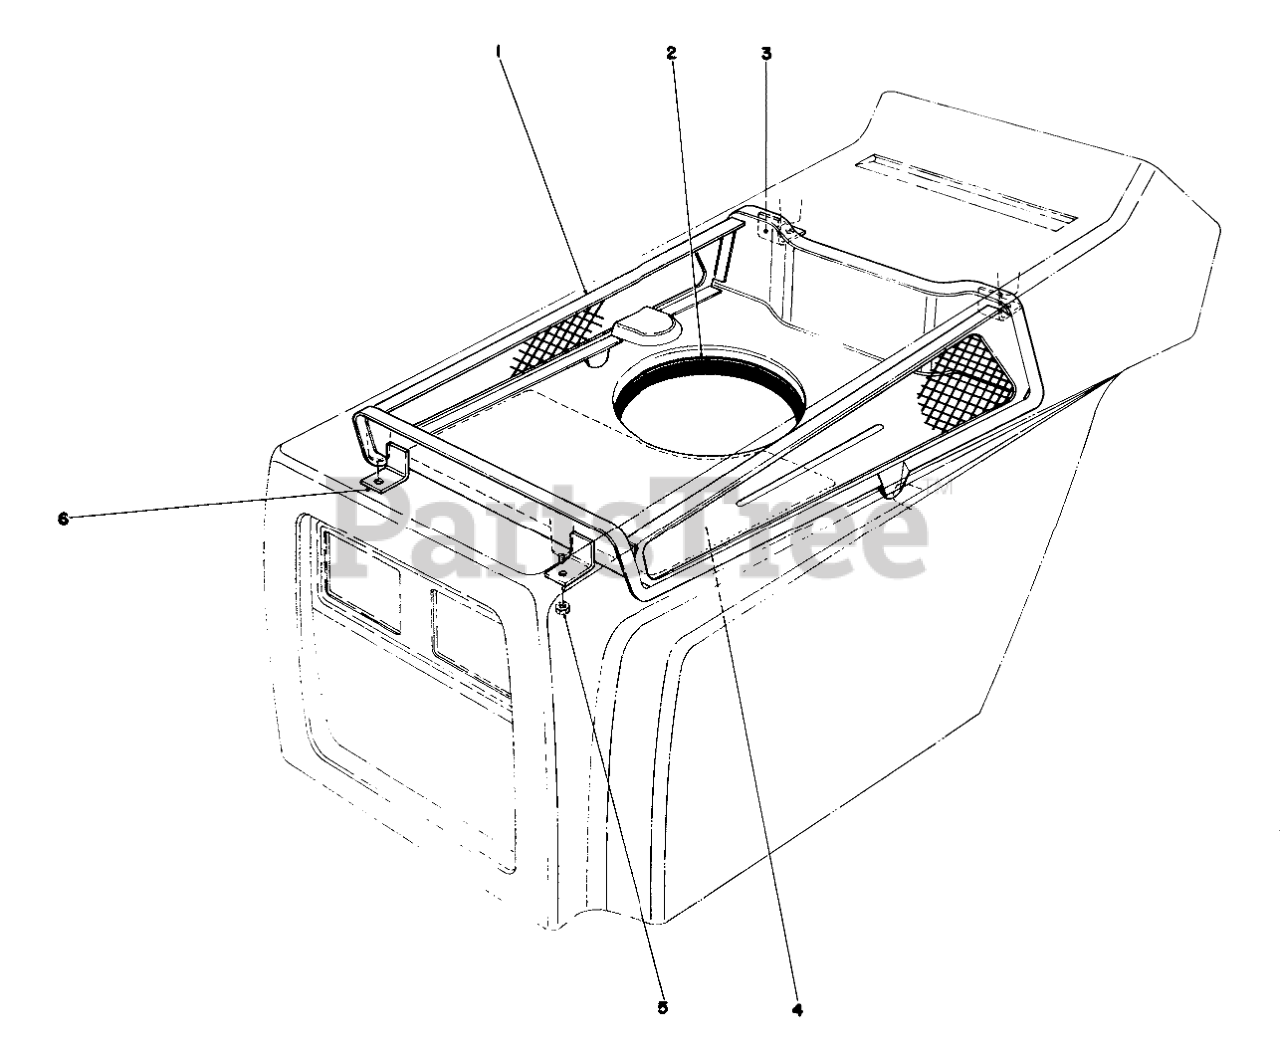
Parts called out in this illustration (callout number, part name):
1	Duct Hood
2	Seal Engine
3	Bracket Rear Duct Support
4	Decal Service
5	NUT-LOCK, CONE
6	Bracket Duct Support
